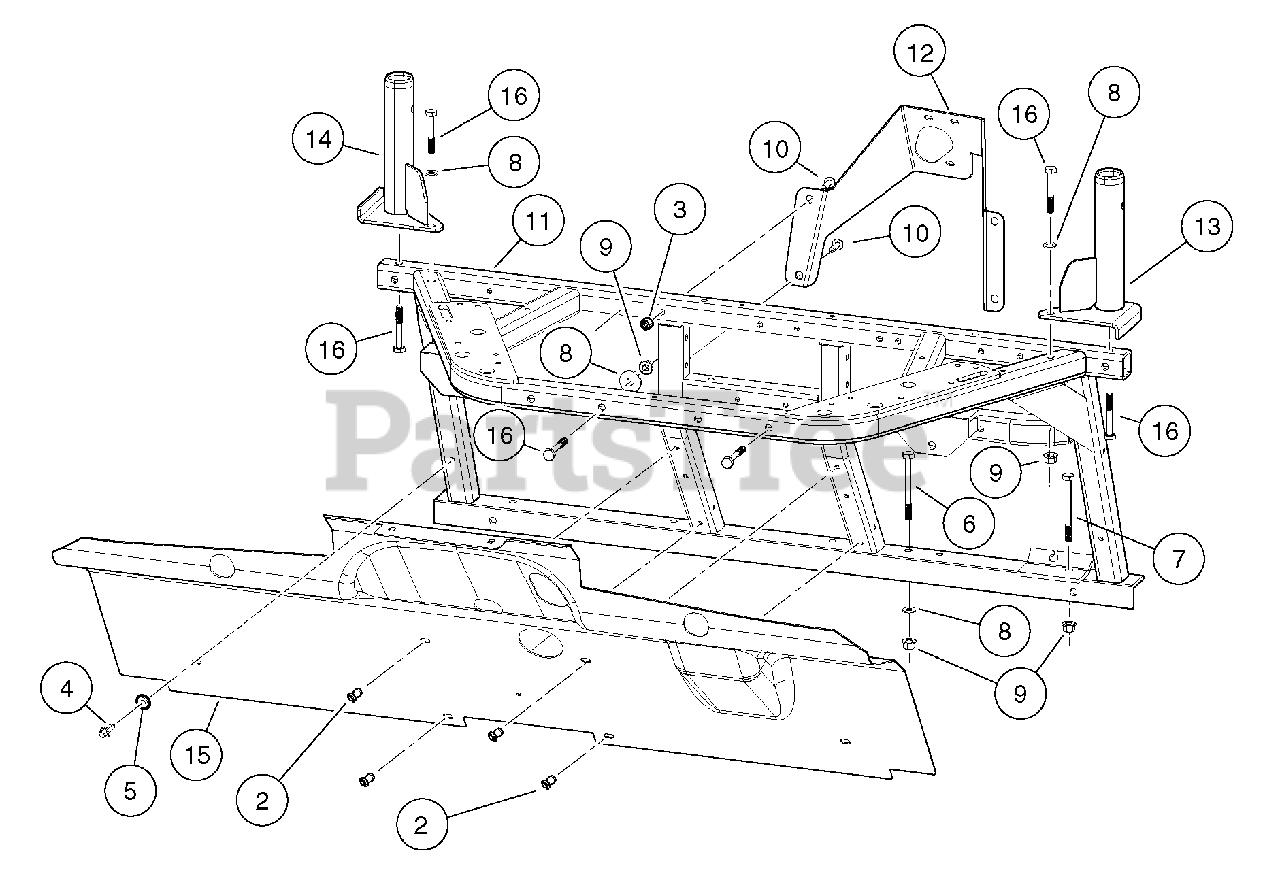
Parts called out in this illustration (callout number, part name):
1	Instl, Cowl Weldmnt/Splash Guard
2	Blind Rivet, Push Type
3	Nut,m8,all Metal Lock
4	M8-1.25x20 Taptite
5	Washer, Flat, 3/8, Blk Fin
6	Bolt, M10x1.50x100 (Black)
7	Bolt, M10 X 1.50 X 110 Black
8	Washer Hard,m10
9	Nut Flg M10 X 1.5 Mech Def
10	Bolt Flanged Head, M8 X 1.25 X 65
11	Weldment, Dash, Front
12	Bracket, Column, Steering
13	Weldment, Front, Base, ROPS, Right-Hand
14	Weldment, Front, Base, ROPS, Left-Hand
15	Guard, Splash, Gas Injection
16	Bolt, M10 X 1.50 X 65
